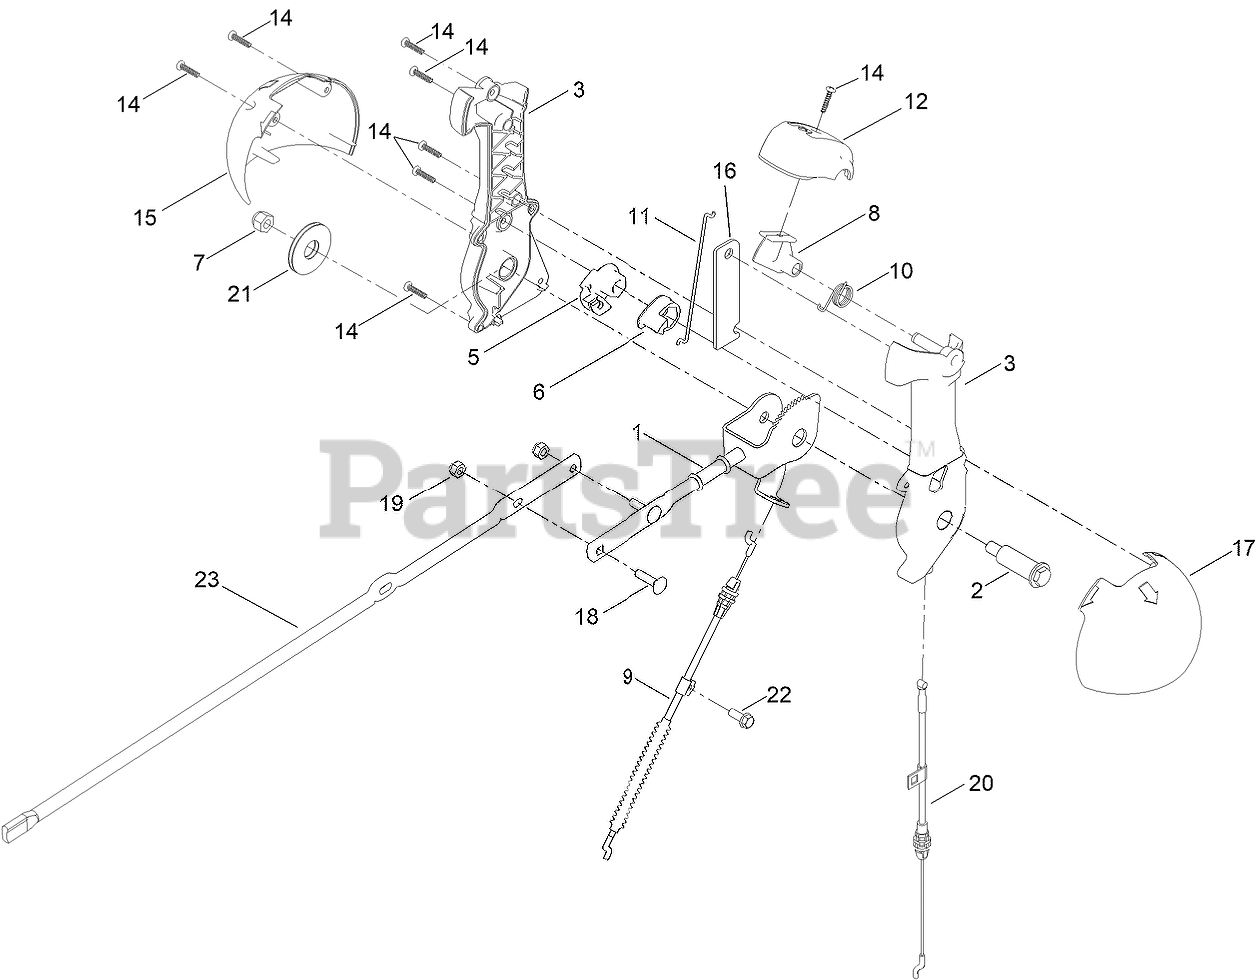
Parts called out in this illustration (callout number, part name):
1	ROD-CONTROL, CHUTE
2	SCREW-SHOULDER, HWH
3	CHUTE CONTROL LEVER ASM
5	LEVER-CABLE, DEFLECTOR
6	PAWL-LATCH
7	NUT-HEX
8	TRIGGER-LATCH
9	CABLE-CONTROL, DEFLECTOR
10	SPRING-TORSION
11	LINK-LATCH
12	CAP-LEVER
14	SCREW-PPH
15	GLOBE-QUICKSTICK, RH
16	PLATE-STIFFNER
17	GLOBE-QUICKSTICK, LH
18	BOLT-CARR
19	NUT-HEX
20	CABLE-ROTATION, CHUTE
21	WASHER-FRICTION, COMPOSITE
22	SCREW-HWH
23	ROD-CHUTE
